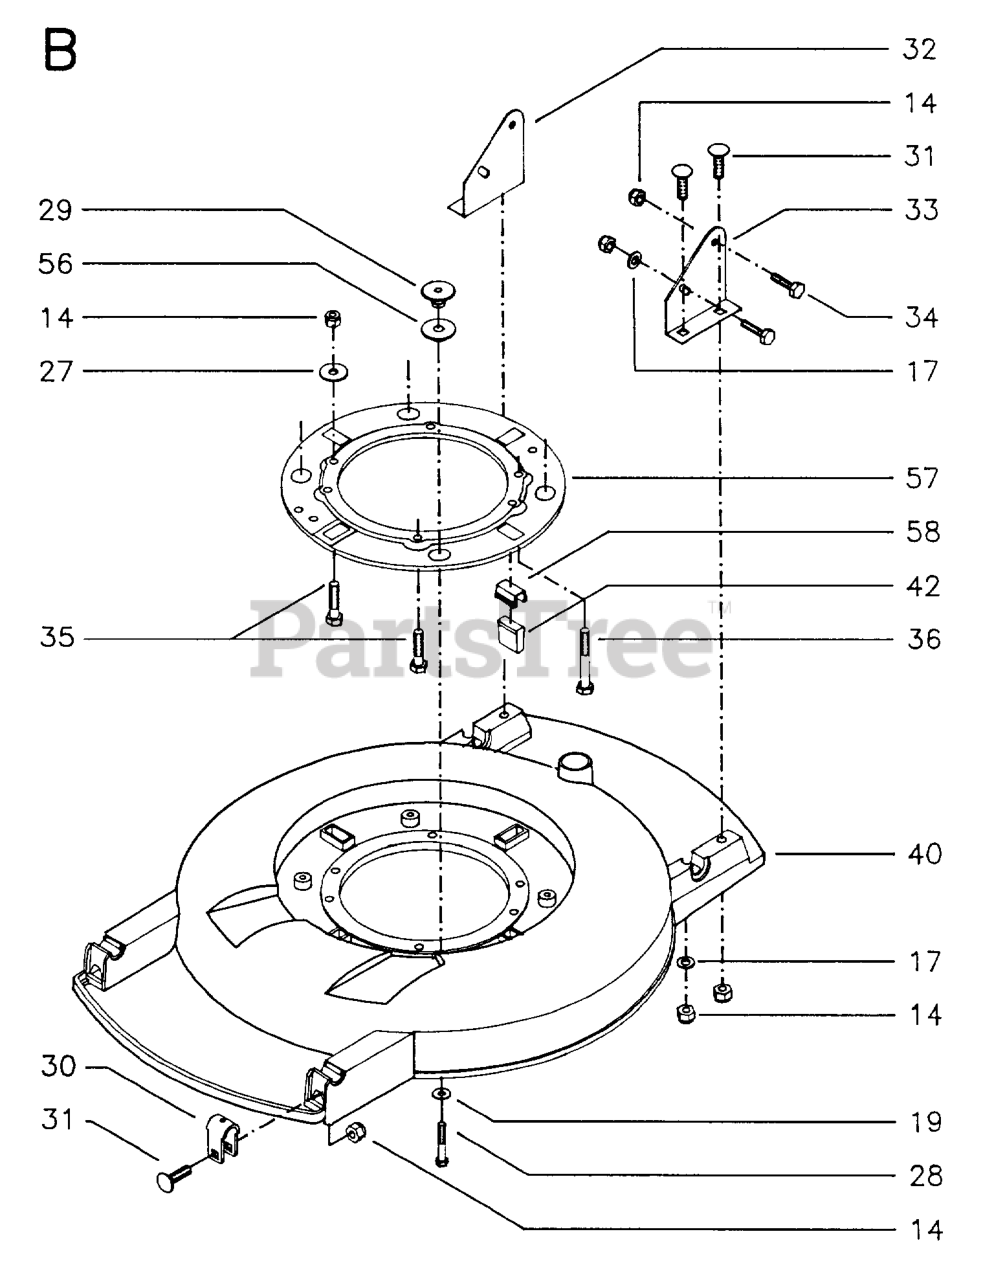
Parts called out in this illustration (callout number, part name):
14	LOCKNUT M8
17	WASHER - 15X7.3X1.6
30	BEARING HOLDER
32	HANDLE BRACKET
33	HANDLE BRACKET
34	BOLT - M8X16
